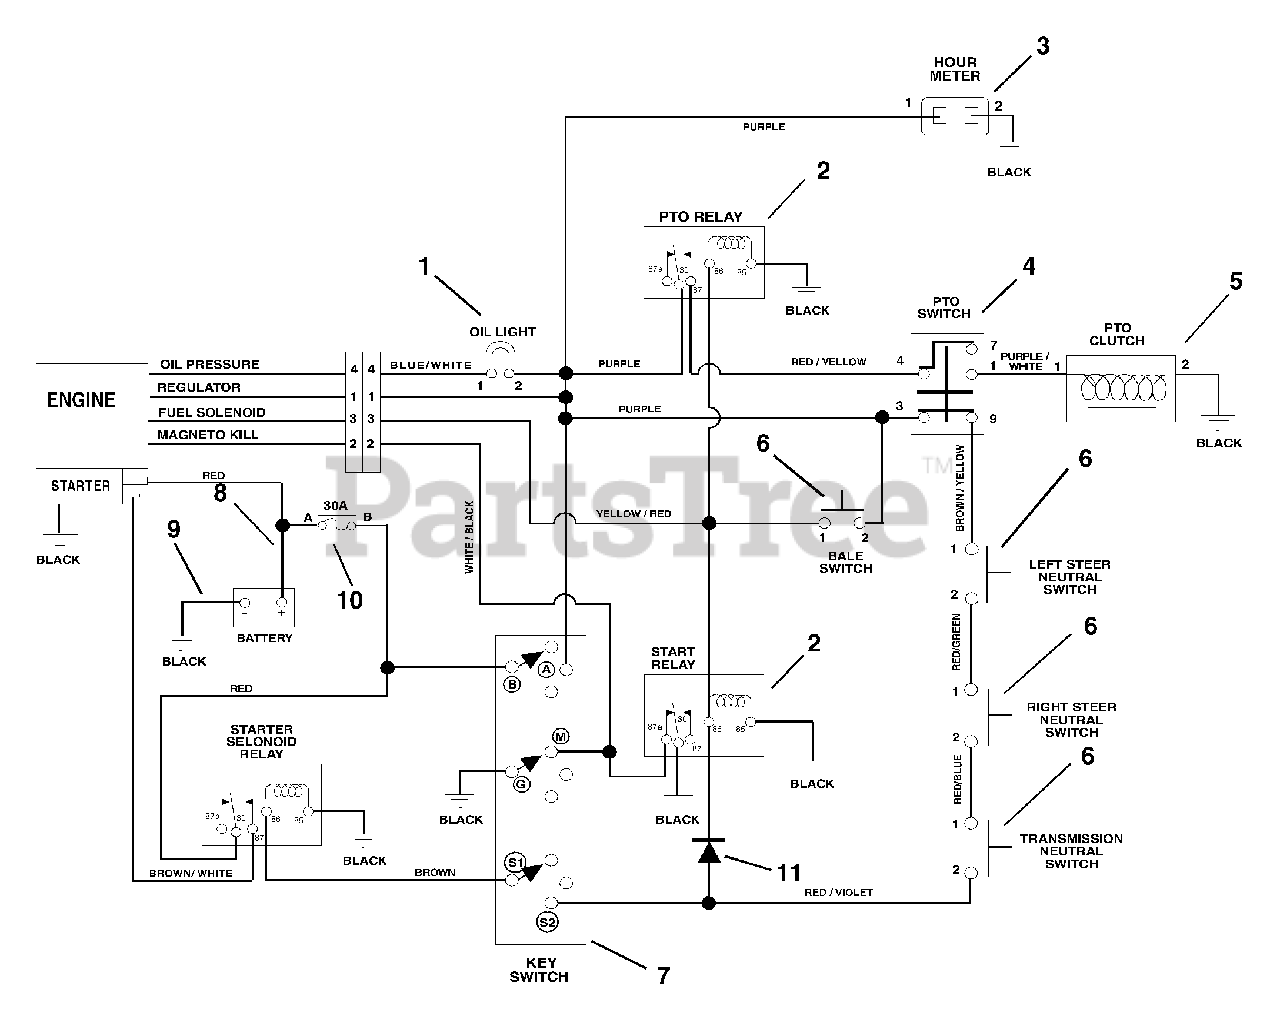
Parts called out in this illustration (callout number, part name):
1	LIGHT, INDICATOR (RED)
2	RELAY
3	METER, HOUR W/MAINTENANCE
4	SWITCH, CLUTCH
5	CLUTCH, ELECTRIC - WARNER
6	SWITCH-SINGLE POLE N.O.W/COVER
7	KEY SWITCH
8	CBL,BATTERY TO SOLENOID
9	CBL,NEGATIVE BATTERY 20.00
10	FUSE, 30 AMP.
11	MOLDED DIODE PLUG 1 AMP
